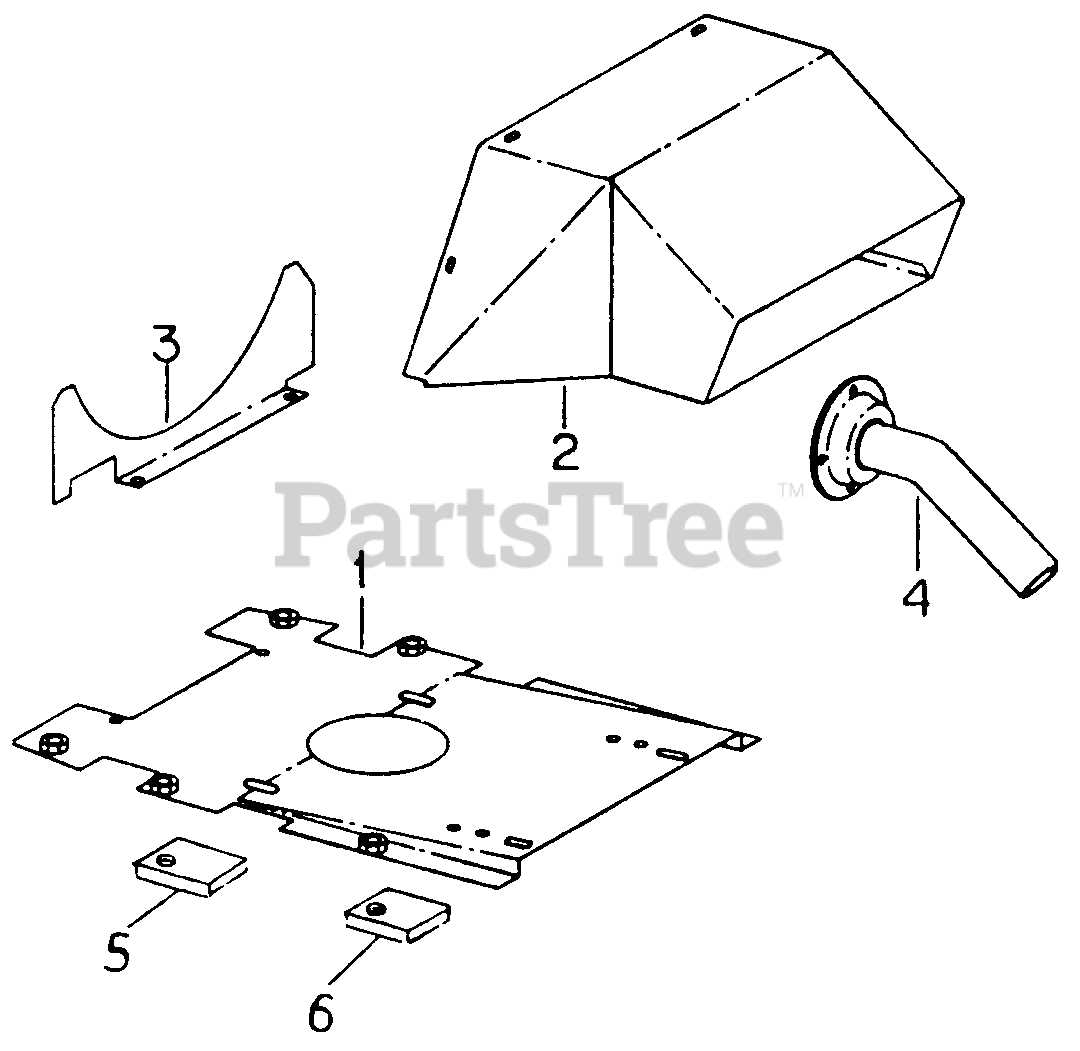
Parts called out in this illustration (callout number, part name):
1	Plate Assy, Eng Mtg
2	Shroud Assy, Engine
3	Shroud, Lower
4	Tube Assy, Exhaust
5	Spacer, Engine Mounting, .060 Thk
6	Spacer, Engine Mounting, .170 Thk
